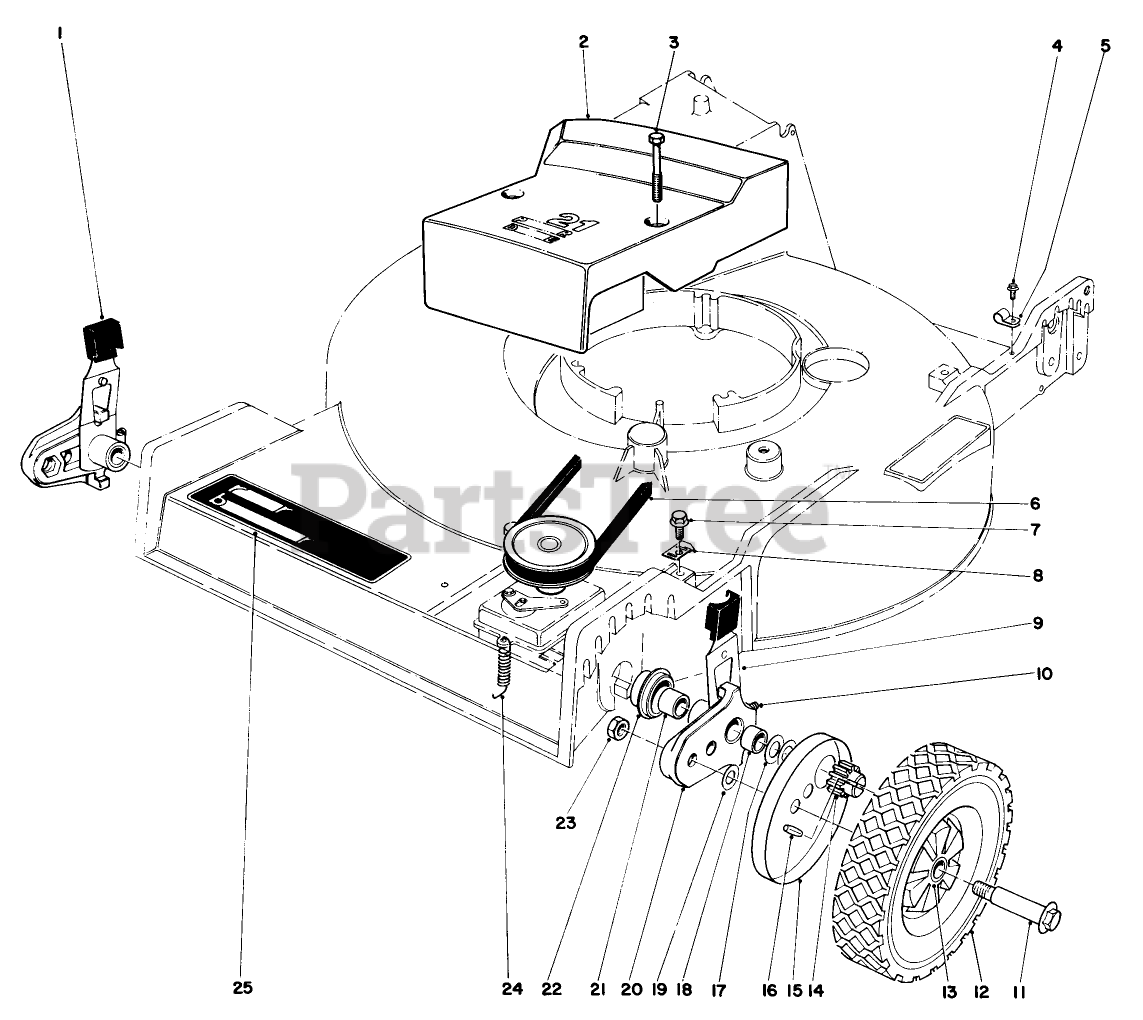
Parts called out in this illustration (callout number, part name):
1	KNOB-ARM
4	SCREW
5	CLAMP-CABLE
6	BELT-V
7	SCREW-THD ROLL, HWH
10	FITTING-GREASE
11	BOLT-WHEEL
12	WHL/GEAR/TIRE PKG
13	BUSHING
14	PINION GEAR 15T
18	BUSHING
19	WASHER
20	PIVOT ARM ASM
21	BUSHING
22	END CAP
24	TENSION SPRING
